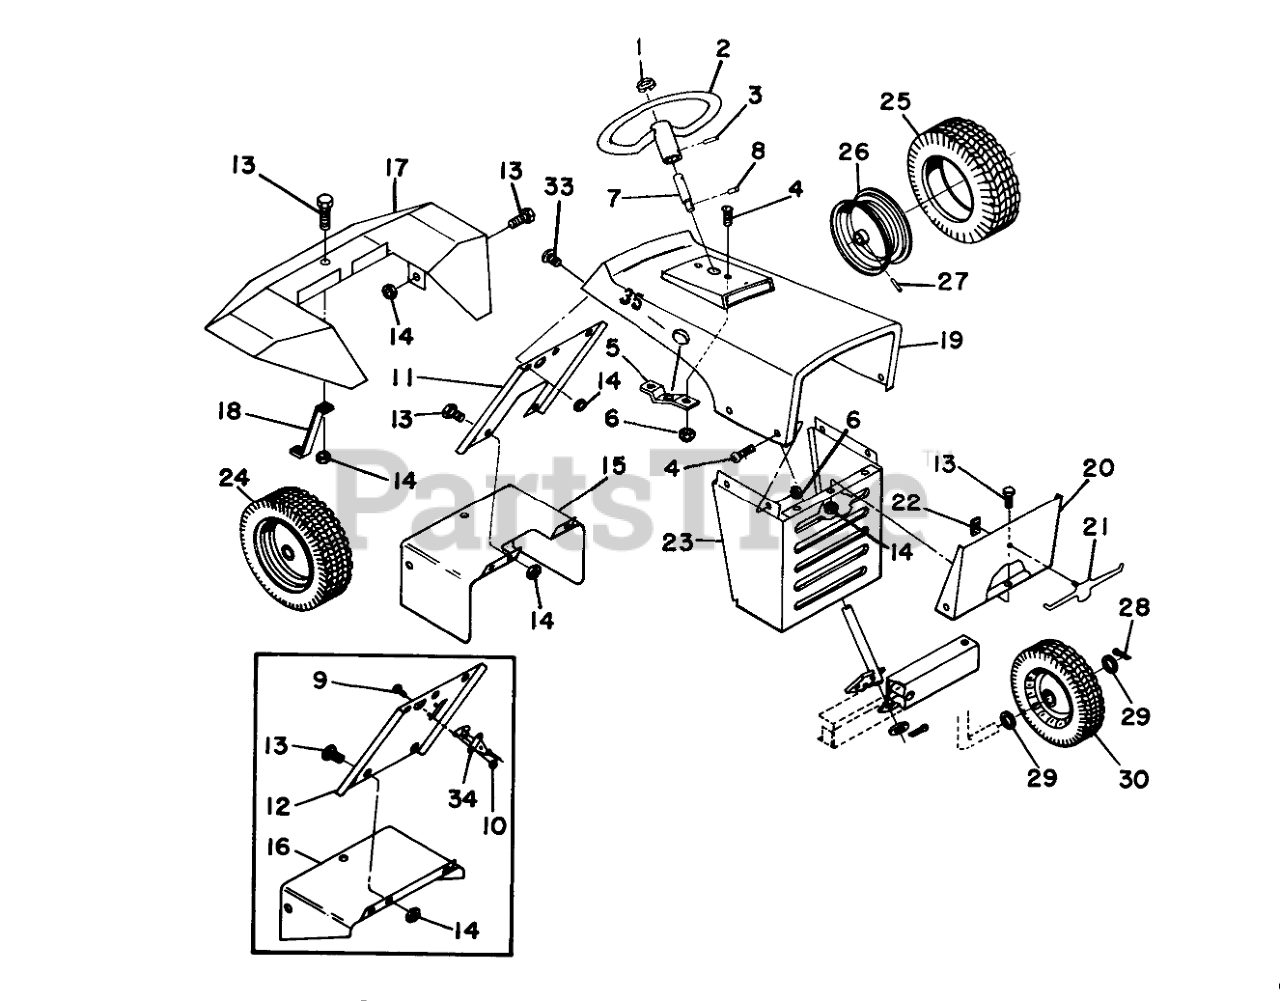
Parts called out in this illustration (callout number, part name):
1	Steering Wheel Cap
1	Plug Button
2	Steering Wheel
3	PIN-SPRING
4	Screw
5	Bracket
7	Extension, Shaft
8	PIN-ROLL
9	Screw
10	NUT-KEPS
11	Hood Support Assy
12	Hood Support Assy
13	SCREW-HH
14	Nut
15	Chain Guard
16	Support, Hood
17	Fender, Rear
18	Support, Fender
20	Grille Panel
21	Bullshead
22	Timmerman Nut
23	Grille Assembly
24	Rear Tire and Wheel Assembly
25	Tire
27	PIN-ROLL, SLOTTED
27	PIN-ROLL
28	PIN-COTTER
29	Washer
30	Wheel
34	Throttle Control
35	Nyliner
